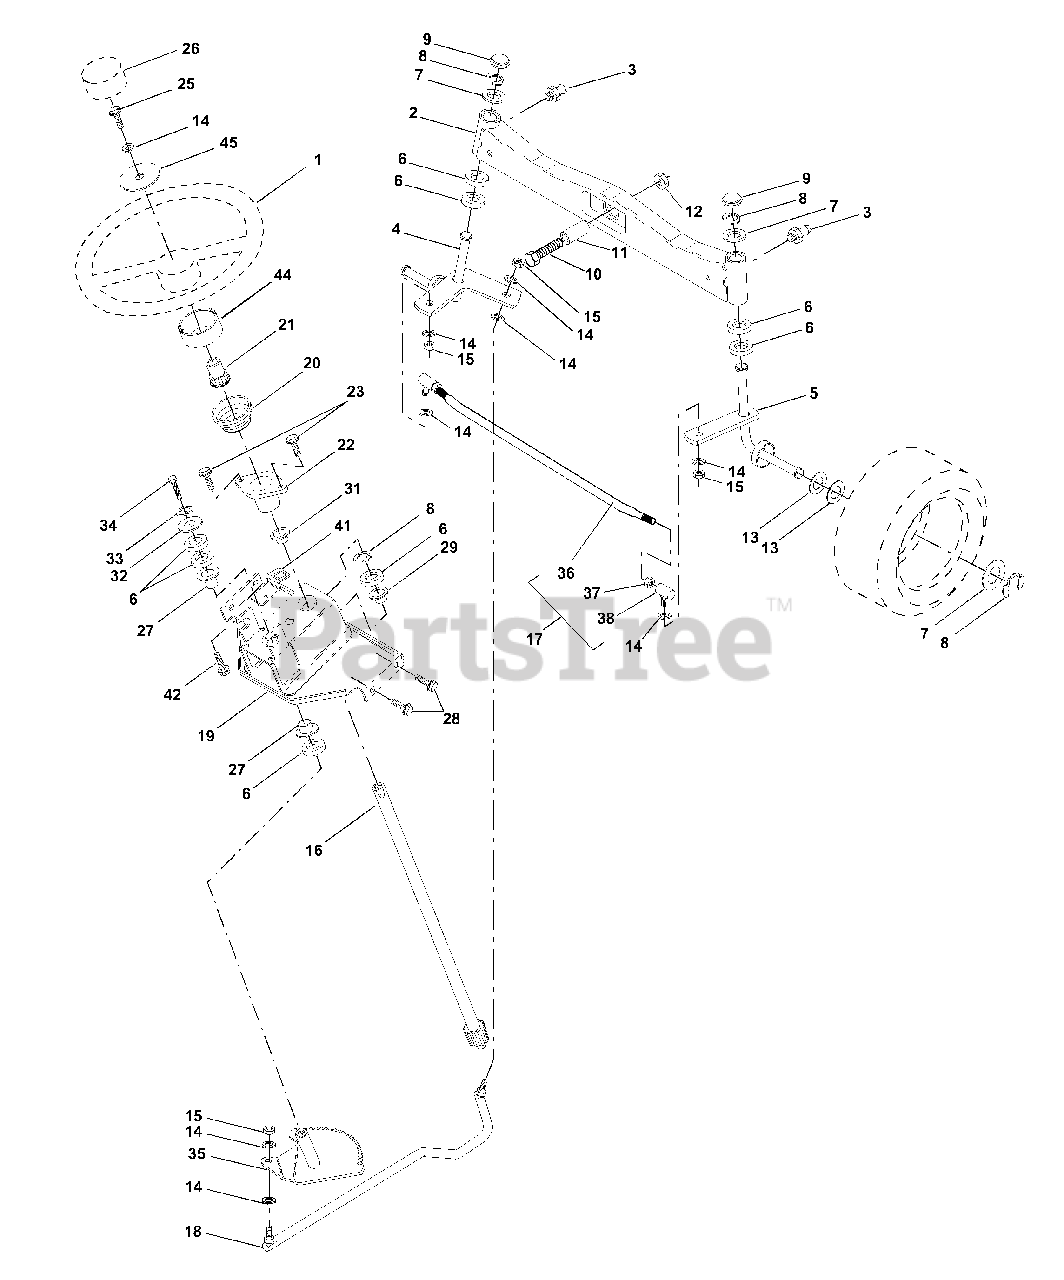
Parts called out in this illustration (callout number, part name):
1	Wheel, Steering
2	Axle Asm., Front
3	Fitting, Grease
4	Spindle Asm, LH
5	Spindle Asm., RH
6	Bearing, Race Thrust Harden
7	Washer 25/32 x 1-5/8 x 16 Ga.
8	Ring, Klip #T5304-75
9	Cap, Spindle
10	Bolt, Fin Hex 5/8-11 x 2-3/4
11	Spacer, Brg. Axle Front
12	Nut, Lock Flange 5/8-11 Unc
13	Washer 25/32 x 1-1/4 x 16 Ga.
14	Washer, Lock Hvy Hlcl Spr 3/8
15	Nut Lock Center 3/8-24 Unf
16	Shaft Asm., Steering
17	Rod Tie Service
18	Draglink, Ball Joint Solid Vgt
19	Support Asm., Steering Vgt
20	Boot Steering Stealth GTYT
21	Adapter, Wheel Steering
22	Bushing, Strg.
23	Screw
25	Bolt, Fin Hex 3/8-16 x 1 Gr. 5
26	Insert Cap Strg WH
27	Bearing, Col. Strg.
28	Screw Hexwsh thdr 3/8-16 x 3/4
29	Bearing, Flange
31	Bushing, Nyliner Snap
32	Washer 11/32 x 1 x 10 Ga.
33	Washer, Lock Hvy Hlcl Spr 5/16
34	Bolt, Hex Hd 5/16-18 x 3/4
35	Gear, Sector Steering
37	Jam Nut RH Thread
38	Joint Asm. Ball RH Thread
41	Bracket Switch Interlock Vgt 97
42	Screw Thdrol 5/16-18 x 1/2 Tyt
44	Extension Steering
45	Washer 13/32 x 1-1/2 x 11 Ga.
